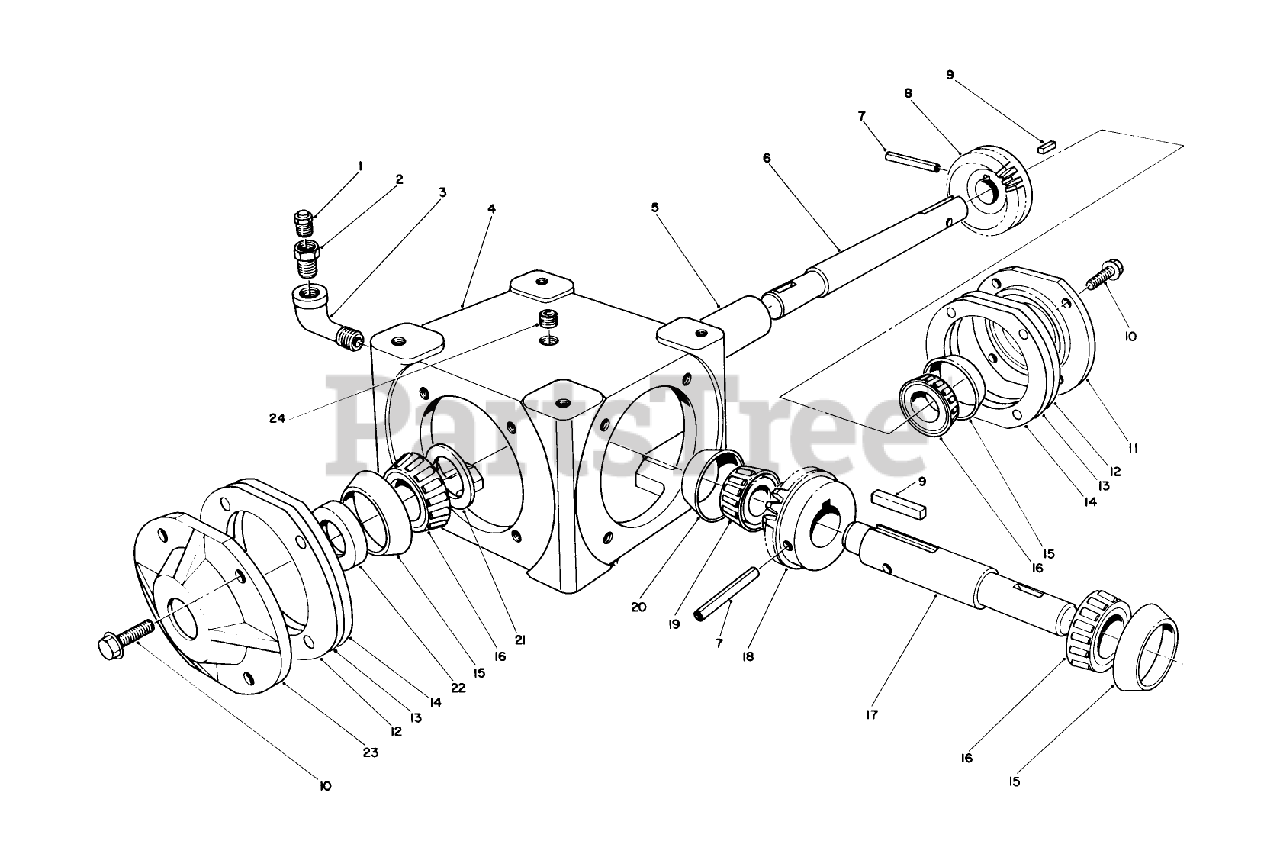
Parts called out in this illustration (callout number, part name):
1	Valve
2	BUSHING
3	Elbow-Street
4	HOUSING
5	SPACER
6	SHAFT
9	Key
10	SCREW-HH (OBS, C/R TO 3234-5)
12	GASKET
13	GASKET
14	GASKET
15	Cup
16	Cone
17	SHAFT
19	Cone
20	Bearing Cup
21	WASHER
22	Seal
24	BELT TENSIONER ROD
